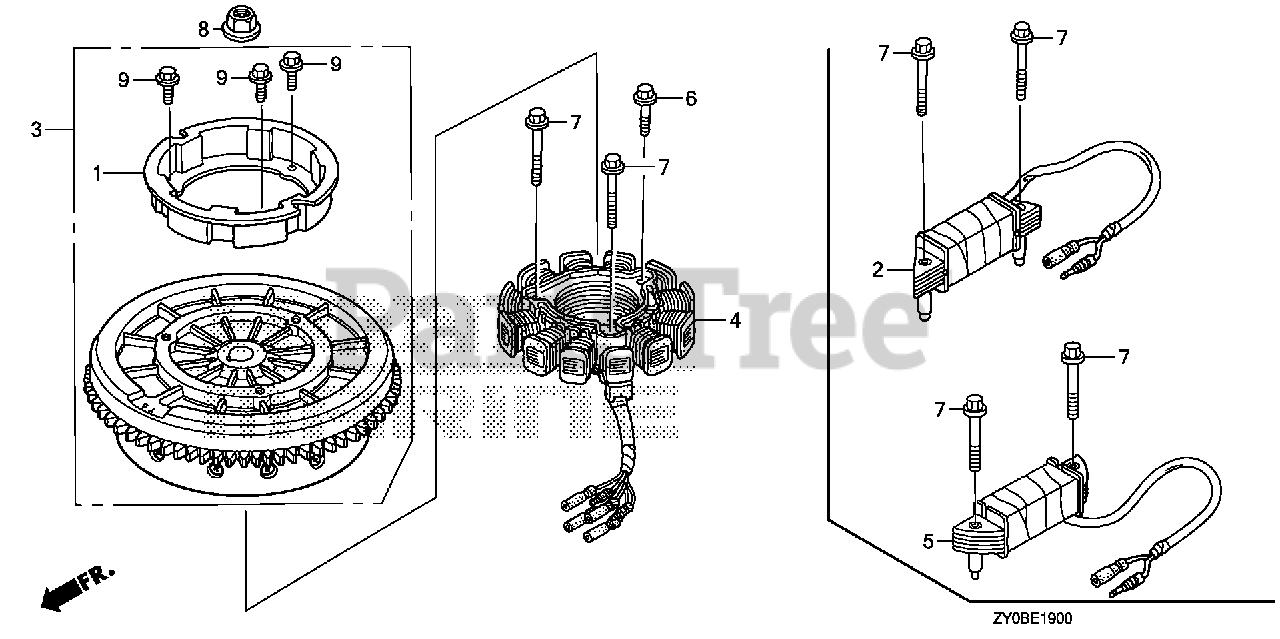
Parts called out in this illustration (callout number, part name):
1	PULLEY, STARTER
3	FLYWHEEL *TBLACK* (SELF STARTER) (BLACK)
4	COIL ASSY., CHARGE (12A)
6	BOLT, FLANGE (6X36) (CT200)
6	BOLT (6X36) (CT200)
7	BOLT, FLANGE (6X52) (CT200)
8	NUT, SPECIAL (16MM)
9	BOLT, FLANGE (6X10)
